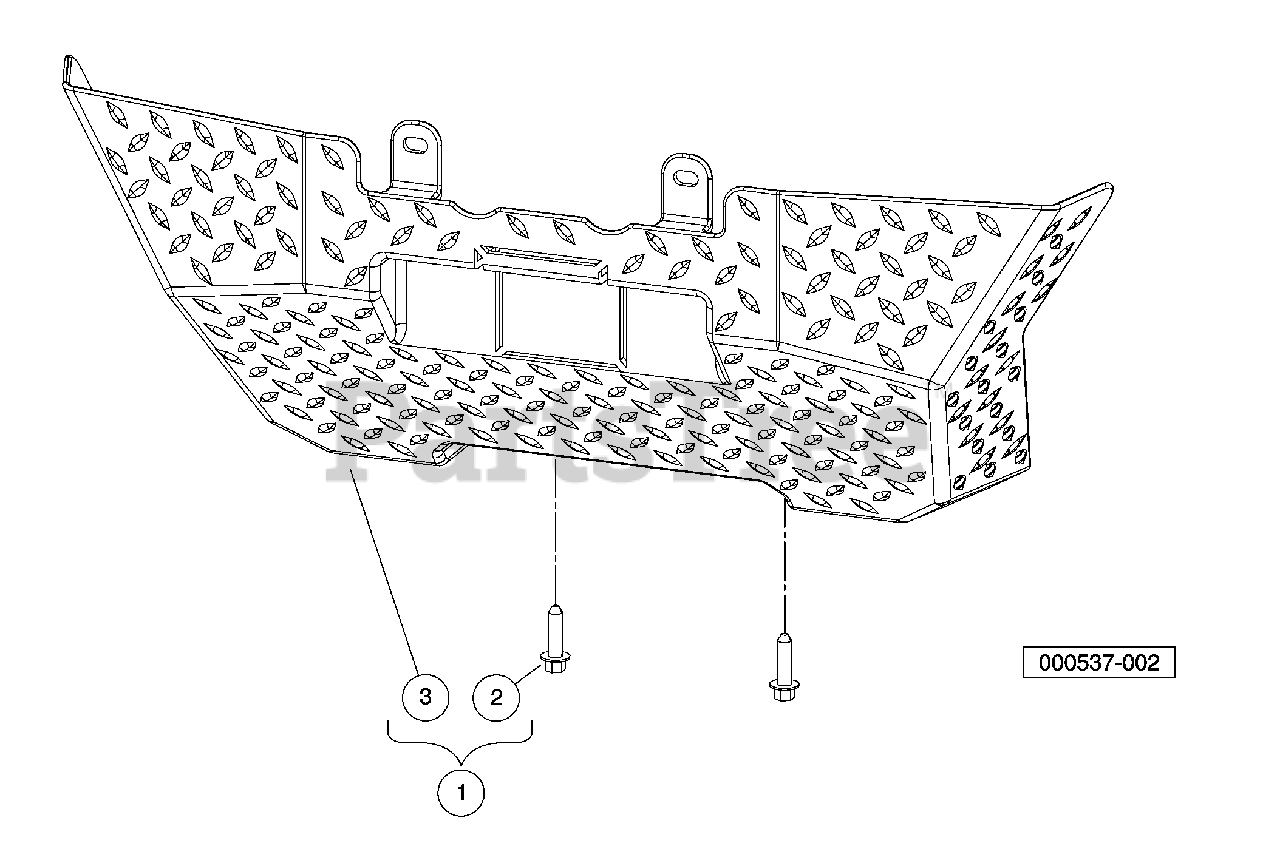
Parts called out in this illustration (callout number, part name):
1	Instl, Skid, Std
2	Screw, M8X1.25X30, Hex
3	Plate, Skid, Std
